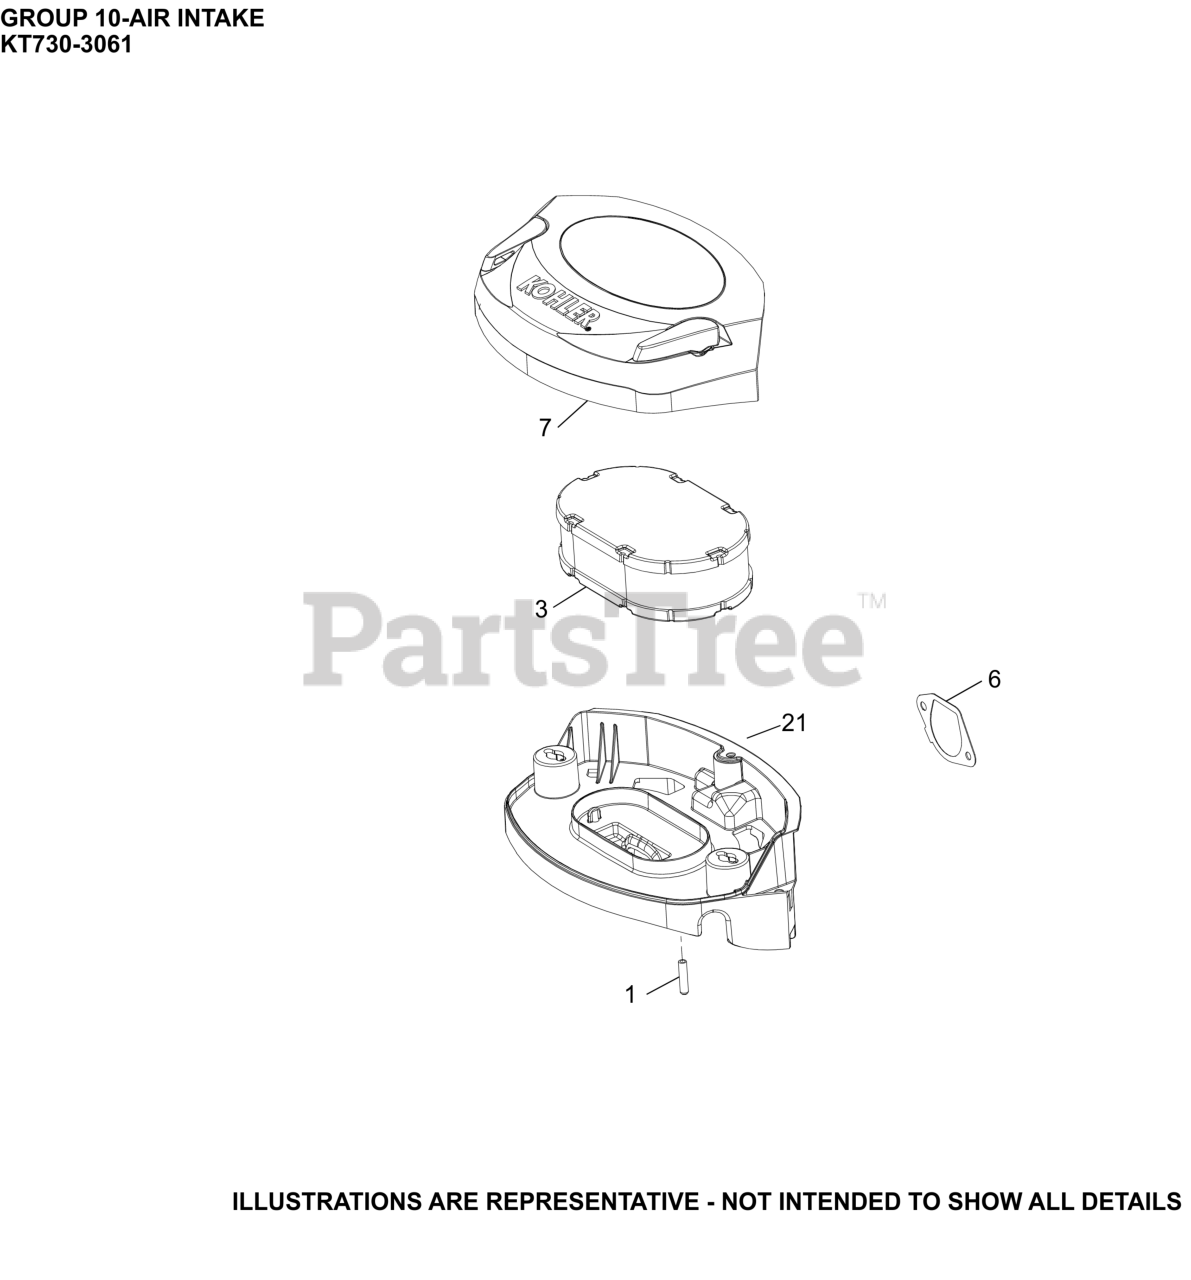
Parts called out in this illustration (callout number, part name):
1	CAP, MASKING
3	ELEMENT, AIR FILTER
6	GASKET, AIR CLEANER BASE
7	COVER ASSEMBLY, AIR CLEANER
21	BASE ASSEMBLY, AIR CLEANER
